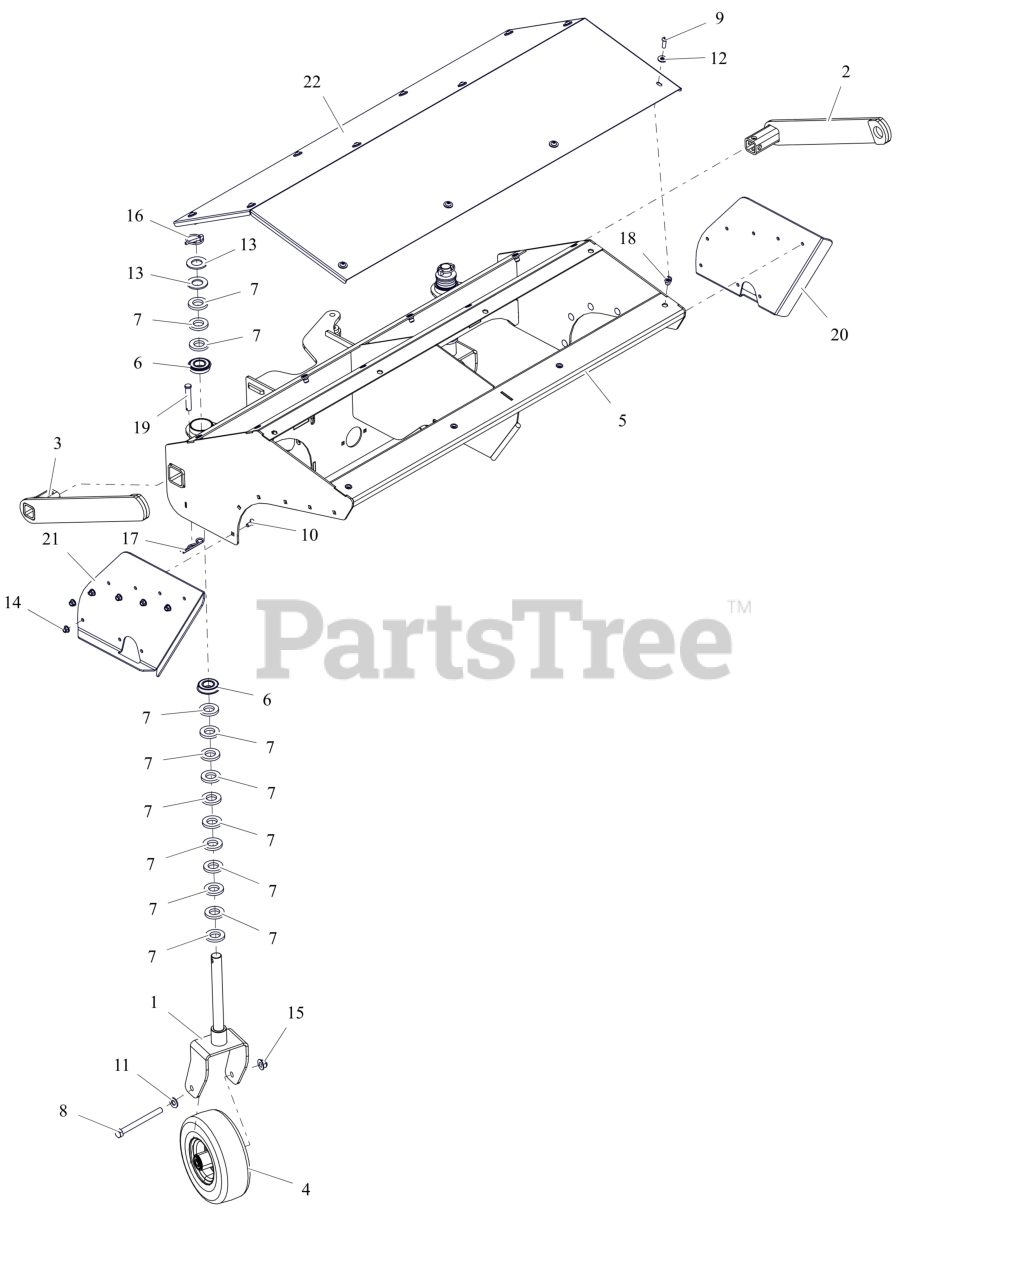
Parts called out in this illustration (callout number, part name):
1	WLDMT, BRUSH CASTER
2	WLDMT, BRUSH STAND, LH
3	WLDMT, BRUSH STAND, RH
4	WHEEL, CASTER
5	WLDMT, BRUSH FRAME W/ZERKS
6	BEARING, BALL -2.000 OD X 1.000 ID X .5625 W/RING
7	SPCR, 1.875 X 1.031 X .25
8	BLT,HEX .50-13X5.50 G5 ZCC
9	BLT,SHCS-BTN .31-18X1.00 ZCC
10	BLT, RHSSN.31-18X.750 G5 ZCC
11	WSHR,FLT .531X1.062X.095 ZCC
12	WSHR,FLT .375X.875X.083 ZCC
13	WSHR, FLT 1.062X2.000X.134 ZCC
14	NUT,LK-NYL-FLG .31-18 G5ZC120
15	NUT,NYL-FLG .50-13 GF ZCC
16	PIN, LYNCH .25X1.562 ZCC
17	PIN, HAIR .148"x3-0"LG
18	RVT, HEX 5/16-18 SHORT
19	PIN, CLEVIS .50 X 2.375
20	PLATE, BRG MOUNT LH
21	PLATE, BRG MOUNT RH
22	COVER, TOP - W/DECAL
